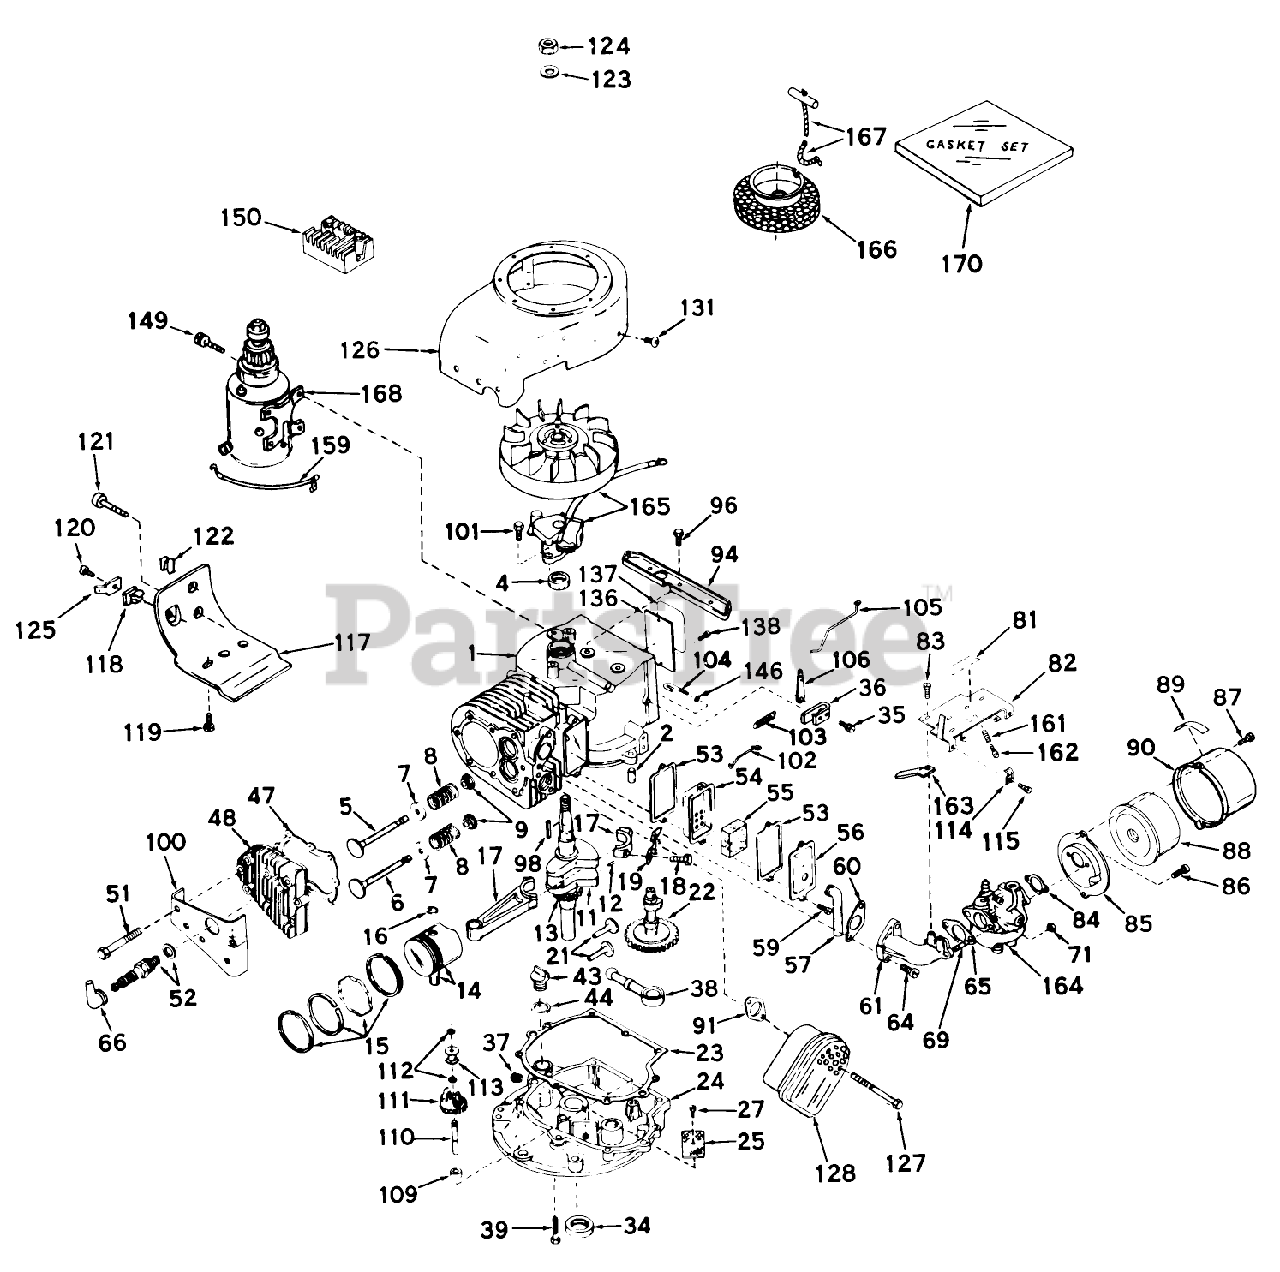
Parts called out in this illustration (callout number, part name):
1	Cylinder Assy. (Incl Nos. 2 4)
2	Pin-Dowel
4	Oil Seal
5	Valve, Intake (Standard)(Incl. No. 9)
5	Valve, Intake (1/32" oversize)(Incl. No. 9)
6	Valve, Exhaust (Standard)(Incl. No. 9)
6	Valve, Exhaust (1/32" oversize)(Incl. No. 9)
7	Cap-Spring, Valve
8	Spring-Valve
9	Keeper-Spring, Valve
11	Crankshaft Assy. (Incl. Nos. 12 13)(Model 935E only)
12	Pin, Groove
13	Gear-Crankshaft
14	Piston Pin Assy. (Incl. 2 of No. 16)(Standard)
14	Piston Pin Assy. (Incl. 2 of No. 16)(.010 oversize)
14	Piston Pin Assy. (Incl. 2 of No. 16)(.020 oversize)
15	ORing
15	Ring Set (.010" OS)
15	Ring Set (.020" OS)
17	Rod Assy., Connecting (Incl. Nos. 18 19)
18	Screw, Hex Hd.
19	Plate, Lock
21	Lifter Valve
22	Screw
23	Gasket-Cover, Cylinder
24	Flange Assy., Mounting (Incl. Nos. 25, 27, 34, 37, 43, 44 110)
25	Screen-Oil Filter
27	Screw
34	Seal-Oil
35	Screw
36	Clamp-Lever, Governor
37	Plug-Drain, Oil (SQH 1/4-18)
38	Pump, Oil
39	Screw (1/4-20 x 1-1/4)
43	Plug-Fill, Oil
44	Gasket
47	Gasket-Cylinder Head
48	CYLINDER HEAD
51	Screw
52	SPARK PLUG
53	Gasket-Breather
54	Body-Breather
55	Element-Breather
56	Cover-Valve
57	Tube-Breather
59	Screw
60	Gasket-Intake
61	Pipe-Intake
64	Screw (T-30, 5/16-18x1-3/32)
65	Gasket
66	51005 GIL.ROTARY TI
69	Stud
71	Nut and Lock Washer (1/4-28)
81	Decal, Speed control
82	Control Assy., Speed
83	Screw (10-24 x 9/16)
84	Gasket
85	Bracket
86	Screw (10-32 x 1/2)
87	Screw
88	Element
89	Decal
90	Body
91	Gasket Exhaust
94	Bracket, Blower Housing (Incl. Nos. 131)
96	Screw (1/4-20x19/32)
98	Key-Flywheel
100	Cover, Cylinder head
101	Screw, Hex Hd. Cap, Sems
102	Link Governor Spring
103	Spring Governor
104	Rod, Governor (Incl. Nos. 146)
105	Link Governor
106	Lever-Governor
109	Spacer
110	Shaft, Governor
111	Governor Gear ASM
112	Ring, Retaining
113	Spool-Governor
114	Conduit
115	Screw (10-32 x 3/8)
117	Emnsion, Blower Housing
118	Grommet
119	Screw
120	Screw
121	Screw
122	51004 GIL ROTARY TI
123	Washer
125	Terminal
126	Housing, Blower
127	Screw
128	Muffler
131	Screw, Hex Hd.
136	IDENTIFICATION PLATE
137	480B GIL SNWTHWR O/
138	Stud
146	Washer-Flat
149	Screw
150	Regulator, Rectifier
159	Wire, Ground
161	Spring-Compression
162	Screw
163	Clip
164	Carburetor
165	Magneto, Alternator
166	Hub Screen, Rope Starter
167	Rope Assy., Starter
168	Motor, Starter
170	Gasket Set
